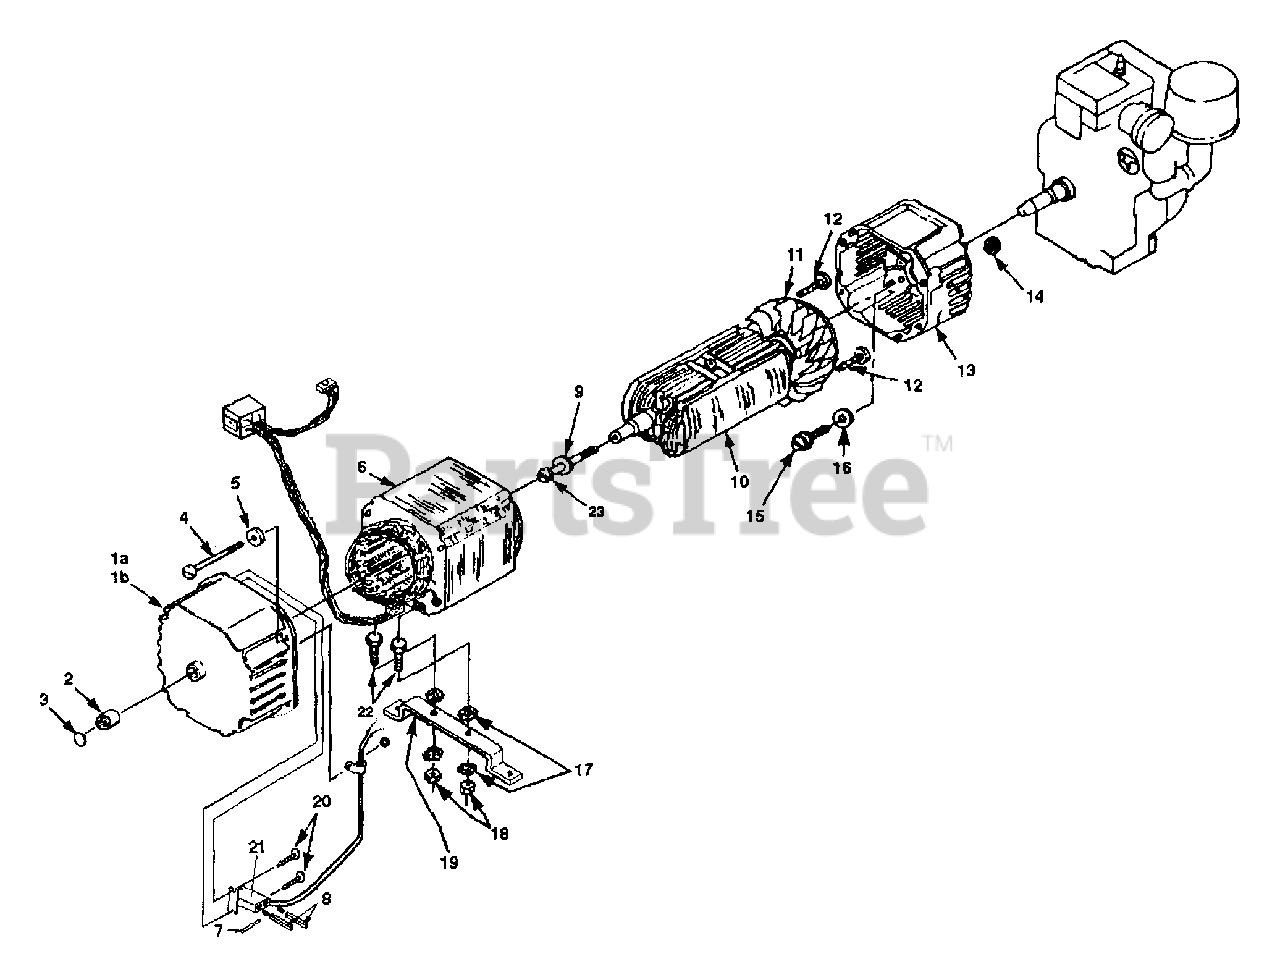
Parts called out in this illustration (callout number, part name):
1A	COMPLETE BRUSH HEAD (LRI2500)
1B	COMPLETE BRUSH HEAD (LRI2500/CSA)
2	BEARING-Needle
3	PLUG-Expansion
4	BOLT-Stator
5	WASHER-Flat (1/4")
6	STATOR & HARNESS
8	BRUSH
9	WASHER-Lock (5/16")
11	FAN-Generator
12	SCREW-Pan Hd. (6-19 X 3/4")
13	END BELL
14	NUT-Hex (1/4-20)
15	SCREW-Hex Hd. (5/16-24 X 3/4")
16	WASHER-Lock
17	WASHER-Lock (int./ext.)
18	NUT-Hex (5/16-18)
19	BRACKET-Generator Support
20	SCREW-Plastite (6-19 X 3/4")
21	BRUSH HOLDER
22	SCREW-Hex Hd. (5/16-18 X 3/4")
23	BOLT-Rotor
